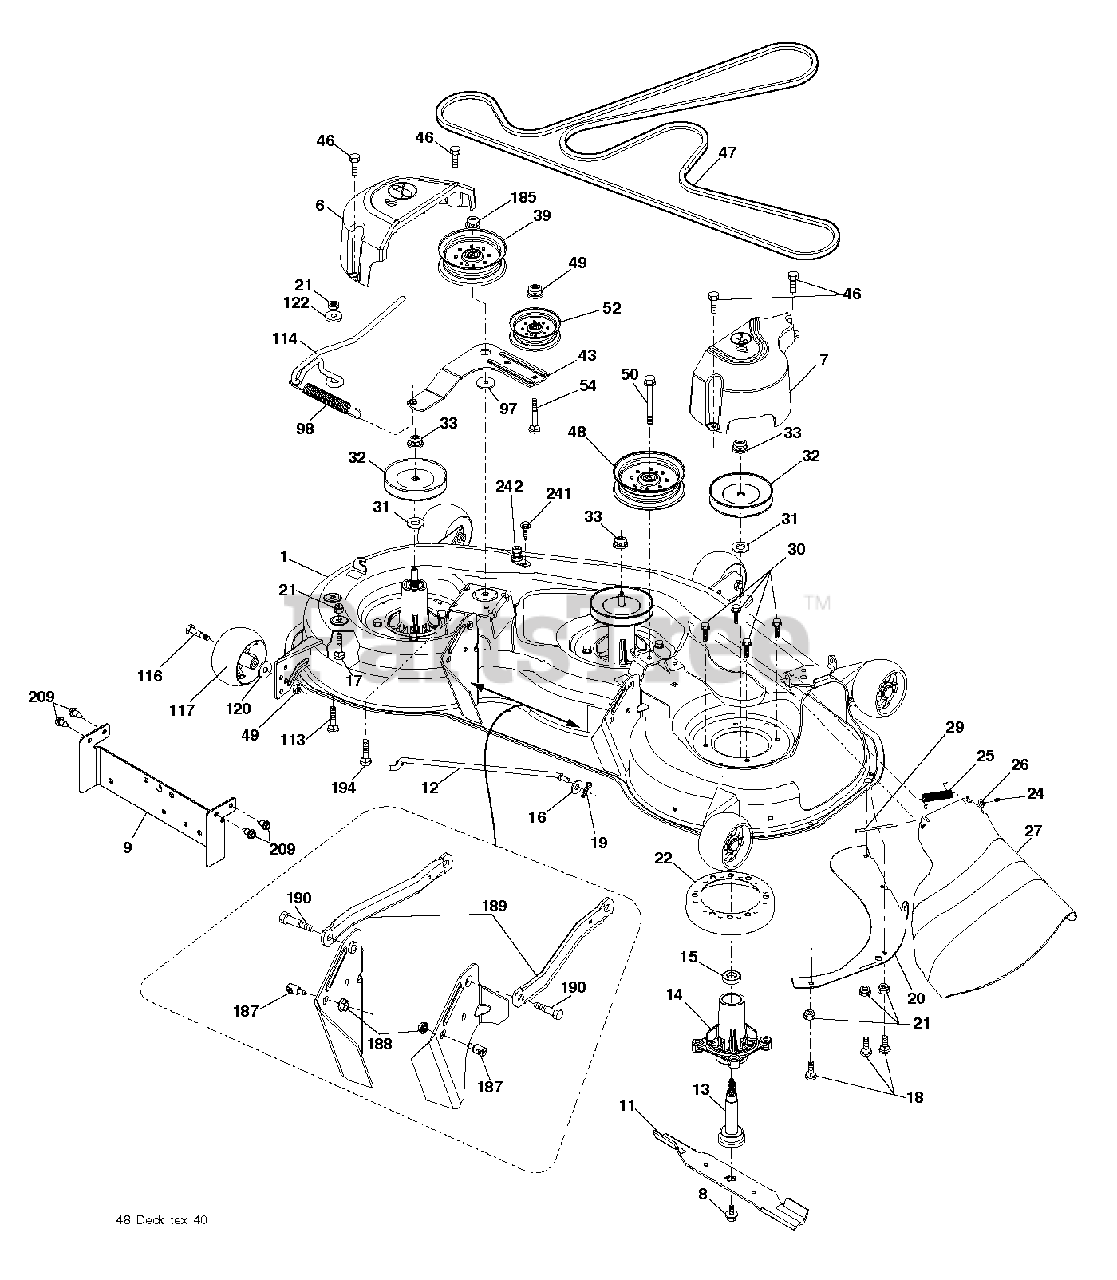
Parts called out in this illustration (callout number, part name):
1	DECK.WELDMENT.48"2006
6	COVER.MANDREL.LH.48"
7	COVER.MANDREL.RH.48"
8	BOLT.WASHER.ASM.7/16-2
9	TORQUE STRAP PNT BLACK
11	48" HI-LIFT BLADE
12	ROD.ANTI.SWAY.48/54"K4
13	SHAFT ASM MANDREL
14	HOUSING.MANDREL.4PT.
16	WASHER
17	BOLT
18	BOLT
19	PIN.COTTER.5/16.BOW TI
20	BAFFLE, VORTEX MWR
21	LOCKNUT
22	STRIPPER.MANDREL.ROUND.BLACK
24	CAP-SLEEVE LT
25	SPRING, TORSION
26	NUT PUSH M
29	ROD.HINGE
30	SCREW, WASHER HEAD
31	WASHER.SPACER.MANDREL
32	PULLEY MANDREL
33	NUT.FLANGE.LOCK.TOP
39	PULLEY.IDLER.4.50/HUB SPECIAL
43	ARM.IDLER
46	SCREW.1/4-20X5/8
47	BELT.DRIVE.DECK
48	PULLEY.IDLER.2006
49	NUT LOCK FLG 3/8-16 UNC
50	SCREW TT 3/8-16X2-1/4 UNC
52	PULLEY.IDLER.48"PRIMARY
54	BOLT.3/8-16X1.50
98	SPRING, DECK DRIVE
113	BOLT CRT
114	ROD.TENSION.RELIEF.TEX (2 2)
116	BOLT.SHOULDER.3/8-16X3-5/8.
117	WHEEL. GUAGE RALLY
122	BUSHING.RELIEF.TENSION
185	NUT.LOCK.FLANGE.7/16
187	STUD.FASTNER.W/ANTI-ROTATE
188	NUT LOCK HEX FLANGE 5/16-18
189	ARM.SUSPENSION.MOWER
190	BOLT.SHOULDER
194	BOLT.HEX.WASHER.HEAD.7/16-24X
209	SCREW
241	SCREW.TT.#10-32X.5.3/8.FLANGE
242	PORT.WASHOUT
